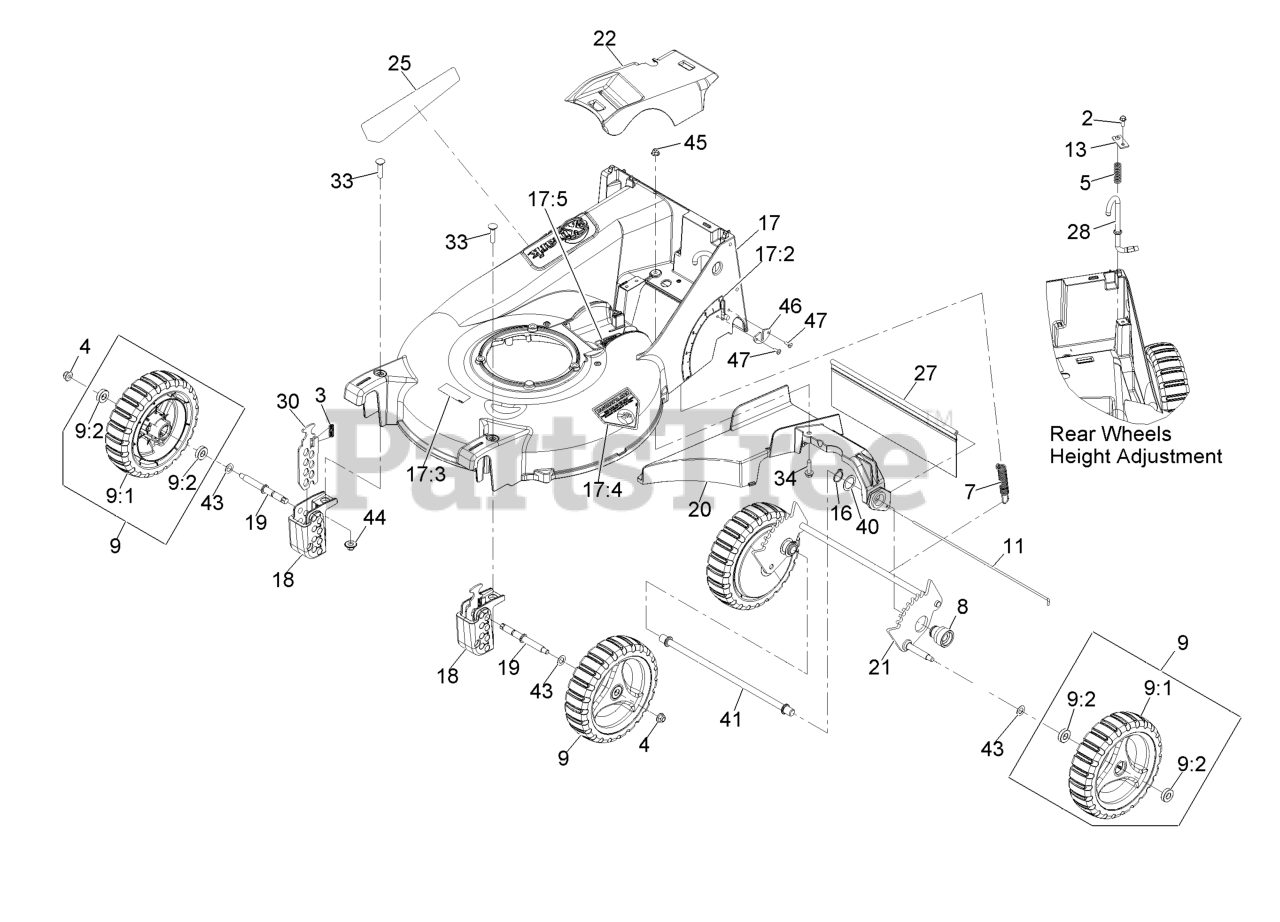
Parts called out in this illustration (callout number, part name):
2	SCREW-HWH
3	SPRING-COMPRESSION
4	NUT-HF, NI
5	SPRING-COMPRESSION
7	SPRING-EXTENSION
9:2	BEARING-BALL
11	ROD,SHIELD
13	BRACKET,MOUNT
16	RING-RETAINING
17	DECK W/DECALS
17:2	DECAL-HEIGHT OF CUT
17:3	DECAL-BLADE
17:4	DECAL-DANGER
17:5	DECAL-COVER MISSING
18	BLOCK,FRONT QUADRANT
19	AXLE-WHEEL
21	WLD,REAR AXLE P21
22	COVER,BELT
25	DECAL-COMM 21 S-SERIES
27	SHIELD-TRAILING P21
28	ROD-HEIGHT ADJ P21
30	PLATE, FRONT HEIGHT
33	SCREW-CARR
34	SCREW-HWHTF
41	SPACER-HOUSING
43	WASHER-PLAIN
44	Nut-Nyloc 3/8-16 Flg
45	NUT-HF, NI
46	PLATE,WEAR
47	RIVET-BLIND
